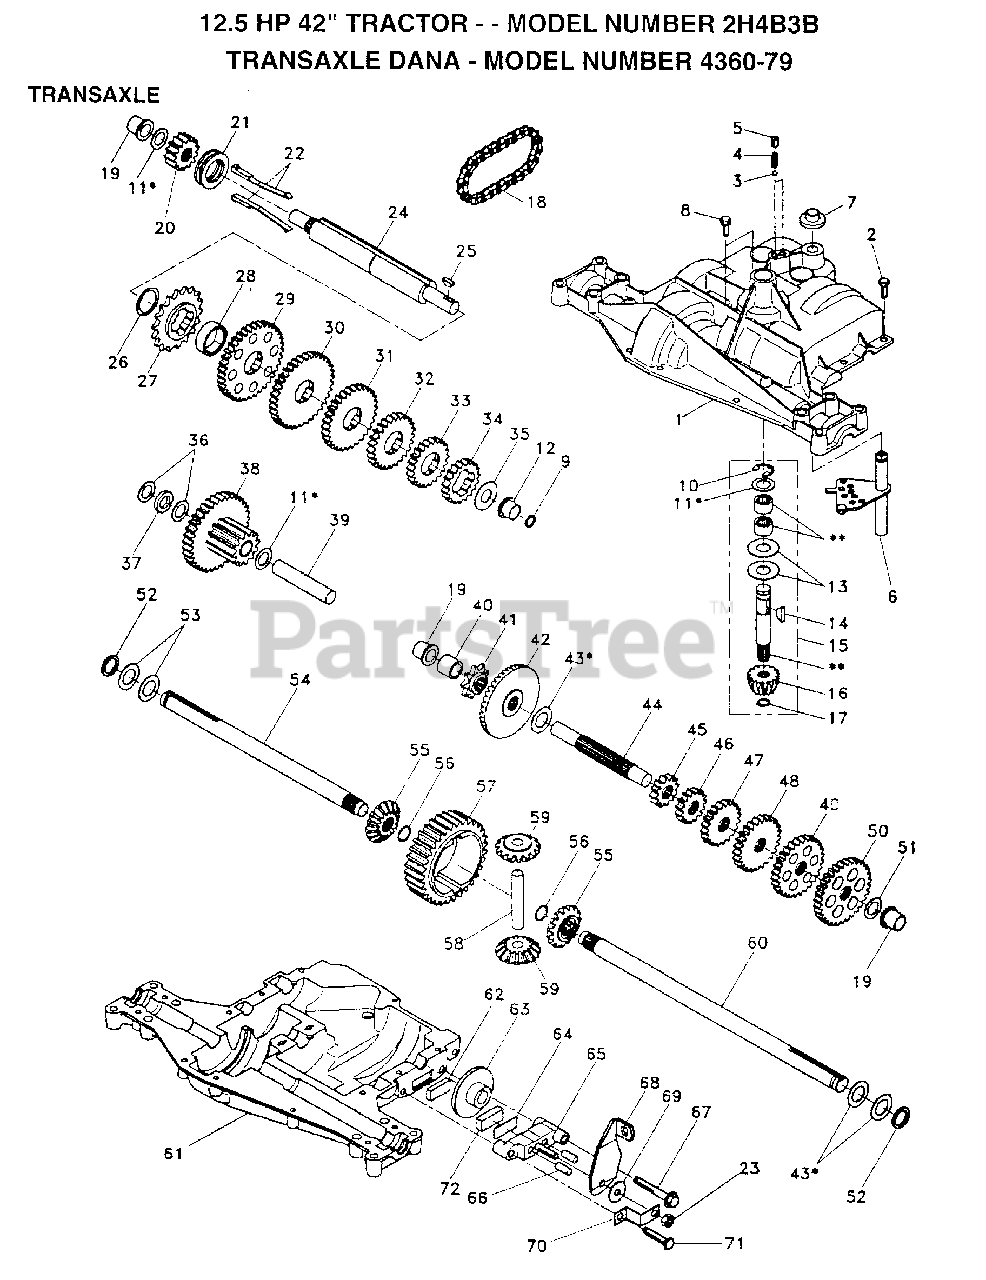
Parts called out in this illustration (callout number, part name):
1	HOUSING UPPER TRN
4	"SPRING, DETENT LT"
5	"SCREW, SET LT"
6	KIT SHIFTER ASM
7	SHIFTER BOOT
8	SCREW TAP W/SEAL
9	SQUARE RING
11	ASM KIT SHIM 4689
12	BEARING FLAN-DANA
13	WASHER T
14	KEY WOODRUFF-DANA
15	AS KIT INPUT SHFT
16	PINION 14T T
17	"RING,RETAINING LT"
18	"CHAIN,24 PTCH LT"
19	BEARING.FLNG.5510
20	GEAR SPUR 14 TTH
21	COLLAR CLUTCH
22	ASM KIT CLTCH KEY
23	NUT.LOCK.5/16-24
24	SHAFT INTERM DANA
25	WOODRUFF KEY
26	"RING,RETAINING LT"
27	SPROCKET 18T T
28	SPACER YT
29	GEAR SPUR 37 TTH
30	GEAR SPUR 35 TTH
32	GEAR 25T LT
33	GEAR SPUR 22 TT
34	SPUR GEAR 19T
35	"WASHER, PLAIN LT"
36	WASHER 025
37	SPACER
38	ASSM GEAR COMB
39	SHAFT IDLER
40	SPACER T
41	SPROCKET 9T LT
43	ASM KIT SHIM
44	SHAFT T
45	GEAR SPUR 12 TTH
46	GEAR SPUR 15 TTH
48	"GEAR, SPUR 25T LT"
49	GEAR 28T T
50	"GEAR, SPUR 31T LT"
51	WASHER 060
52	NEOPRENE WASHER
53	WASHER 031
55	GEAR 15T T
56	"RING,RETAINING LT"
58	SHAFT T
59	GEAR 1ST T
61	HOUSING LOWER TNS
62	PUCK T
63	BRAKE DISC. T
64	SPACER LT
66	PIN T
69	WASHER LT
71	"SCREW, TAPPING LT"
72	PUCK T
